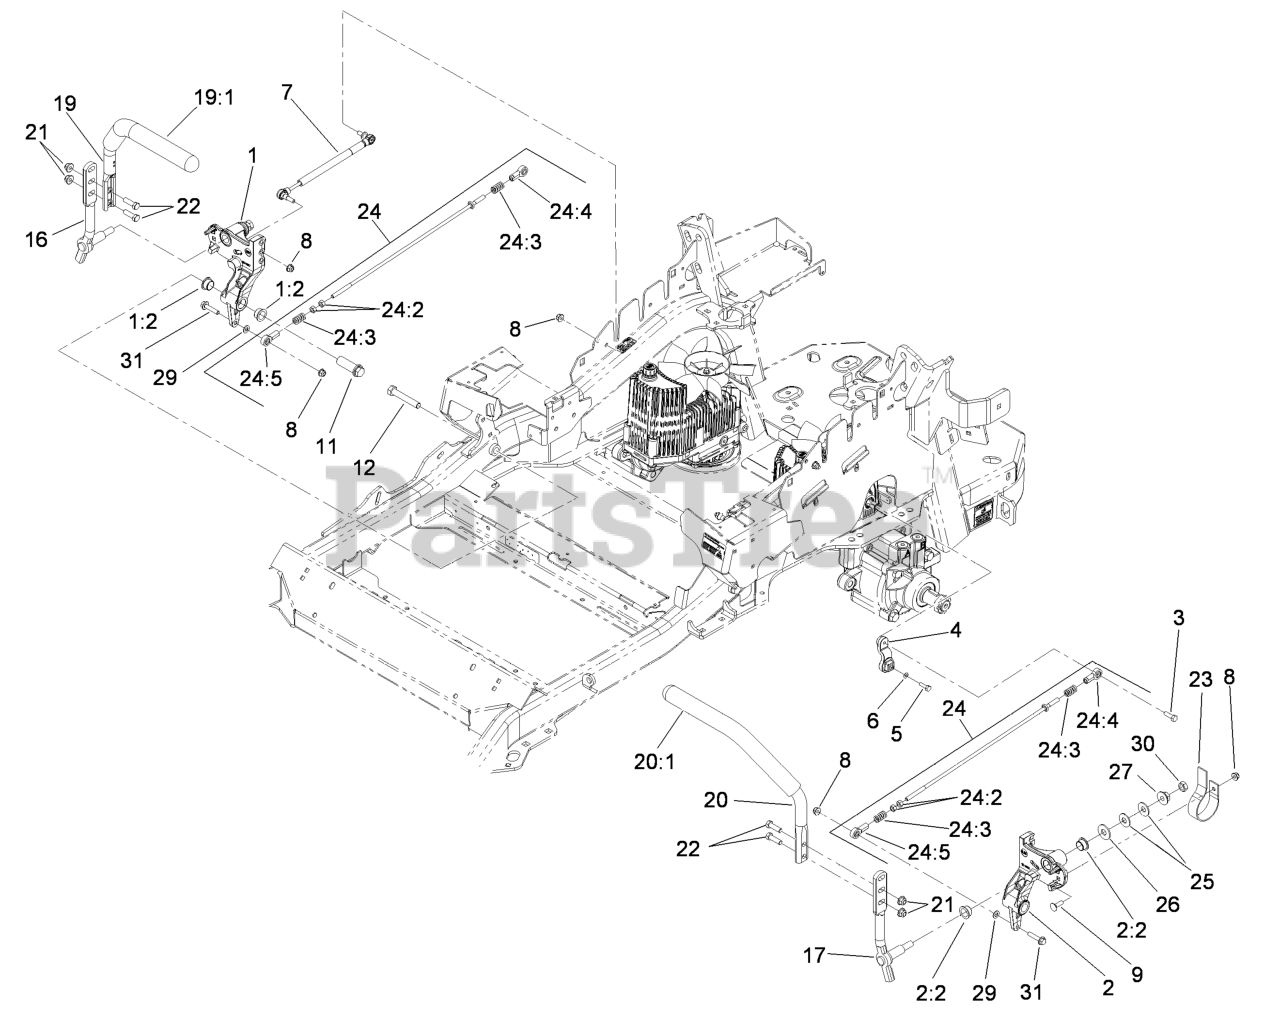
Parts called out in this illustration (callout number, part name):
1	RH MOTION CONTROL AND BUSHING ASM
1:2	BUSHING-FLANGE
2	LH MOTION CONTROL AND BUSHING ASM
2:2	BUSHING-FLANGE
3	SCREW-HH, THREAD LOCKING
4	ARM-CONTROL, PUMP
5	SCREW-HH
6	WASHER-SPRING
7	DAMPER-CONTROL, MOTION
8	NUT-HF, NI
9	BOLT-CARR
11	HUB-THREADED
12	SCREW-HH
16	LEVER-CONTROL MOTION, RH
17	LEVER-CONTROL MOTION, LH
19	RH STEERING HANDLE ASM
19:1	GRIP-LEVER, CONTROL
20	LH STEERING HANDLE ASM
20:1	GRIP-LEVER, CONTROL
21	NUT-HF, NI
22	SCREW-HH
23	SPRING-LEAF
24	FRONT PUMP LINKAGE ASM
24:2	NUT-HEX
24:3	SPRING-COMPRESSION
24:4	BALLJOINT-LH
24:5	BALLJOINT-RH
25	WASHER-SPRING
26	WASHER-FLAT
29	WASHER-PLAIN
30	NUT-JAM
31	SCREW-HHF
